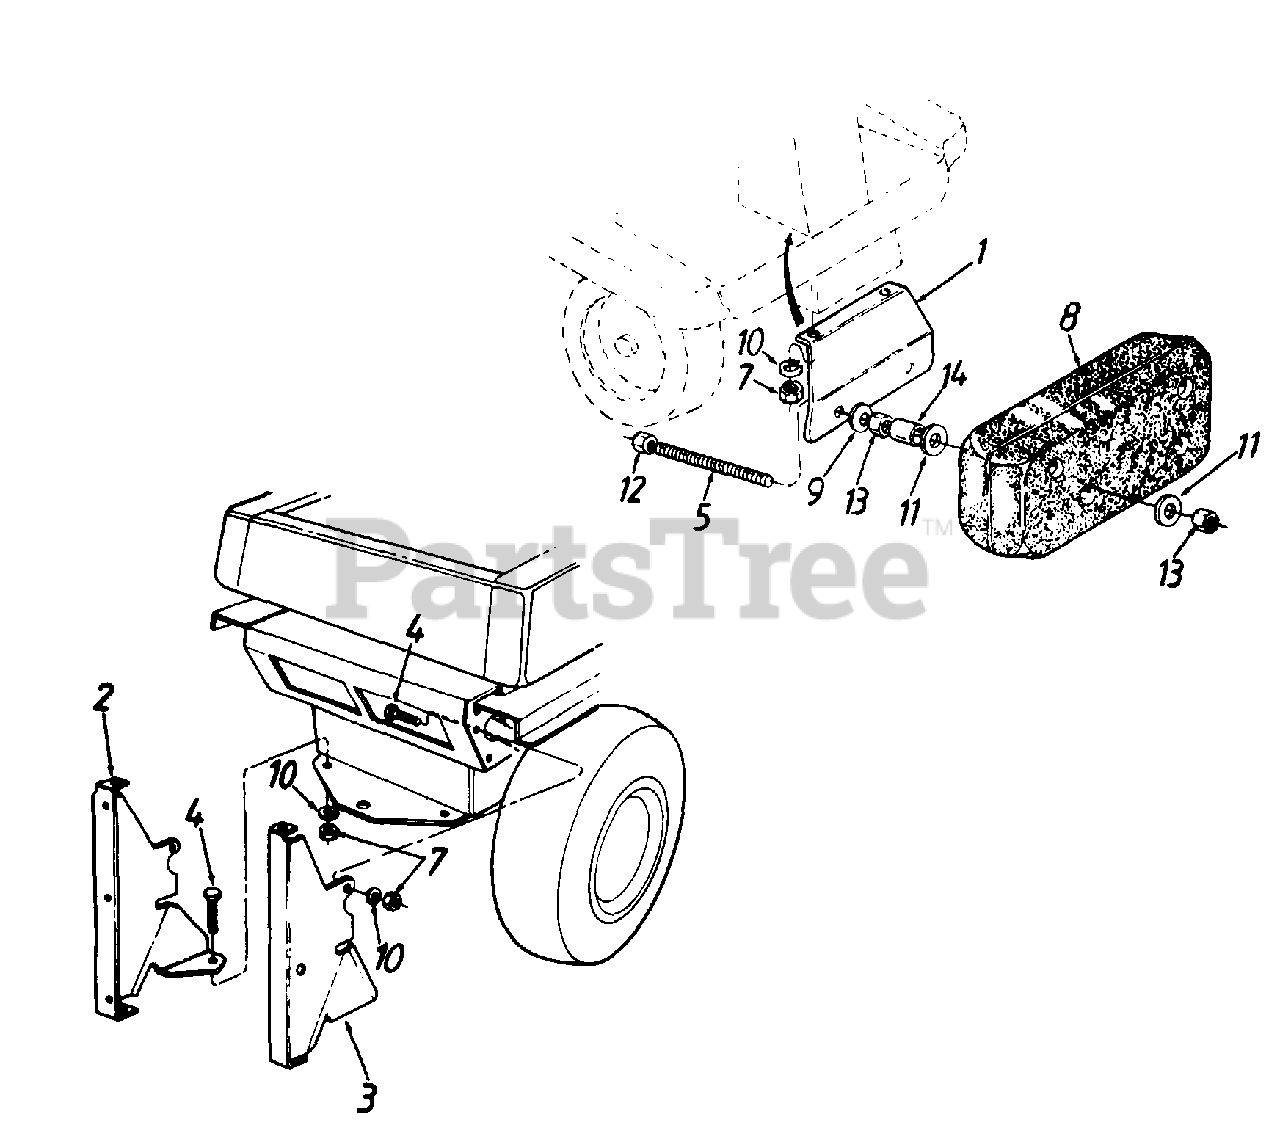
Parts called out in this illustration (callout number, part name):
3	Catcher Support Brkt. - L.H.
4	Hex Bolt 5/16-18 x 1.0" Lg.
5	Stud 7/16-14 x 5-5/8" Lg.
7	Hex Nut 5/16-18 Thd.
8	Front Counterweight
9	Bell-Wash. 7/16" I.D.
10	L-Wash. 5/16" I.D.
11	Fl-Wash. .45" I.D.
12	Hex L-Nut 7/16-14 Thd.
13	Hex Nut 7/16-14 Thd.
14	Spacer
